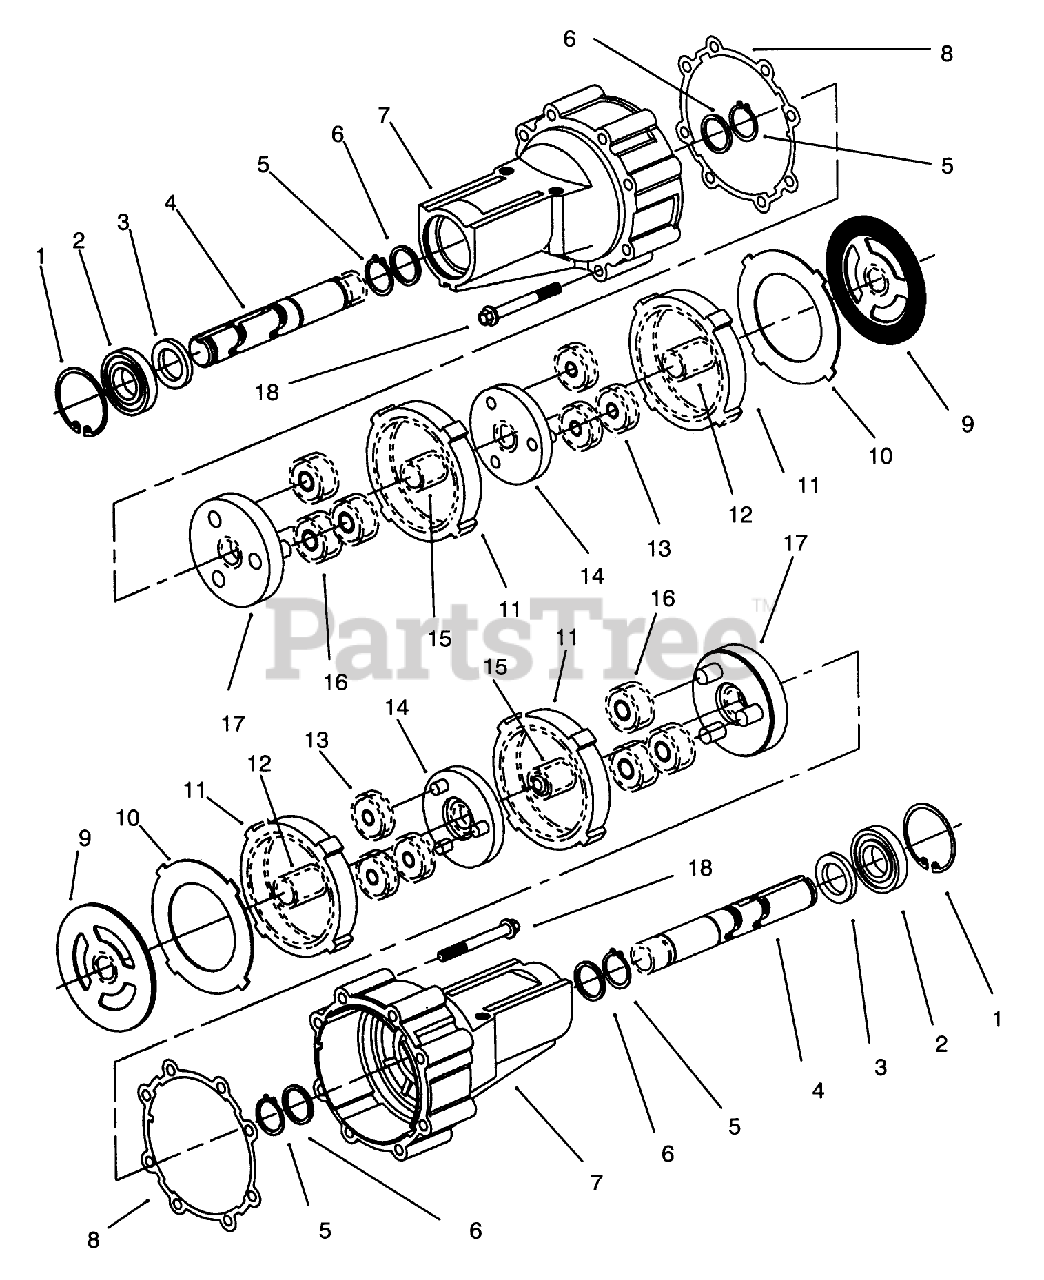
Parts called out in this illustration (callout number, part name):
1	RETAINING RING
2	BALL BEARING
3	RADIAL LIP SEAL
5	RETAINING RING
6	THRUST WASHER
8	AXLE HOUSING GASKET
10	BACKUP PLATE
11	57 TOOTH RING GEAR
12	15 TOOTH FIRST GEAR
13	21 TOOTH PLANET. GEAR
14	15 TOOTH PRIMARY CARR.
15	15 TOOTH SECOND GEAR
